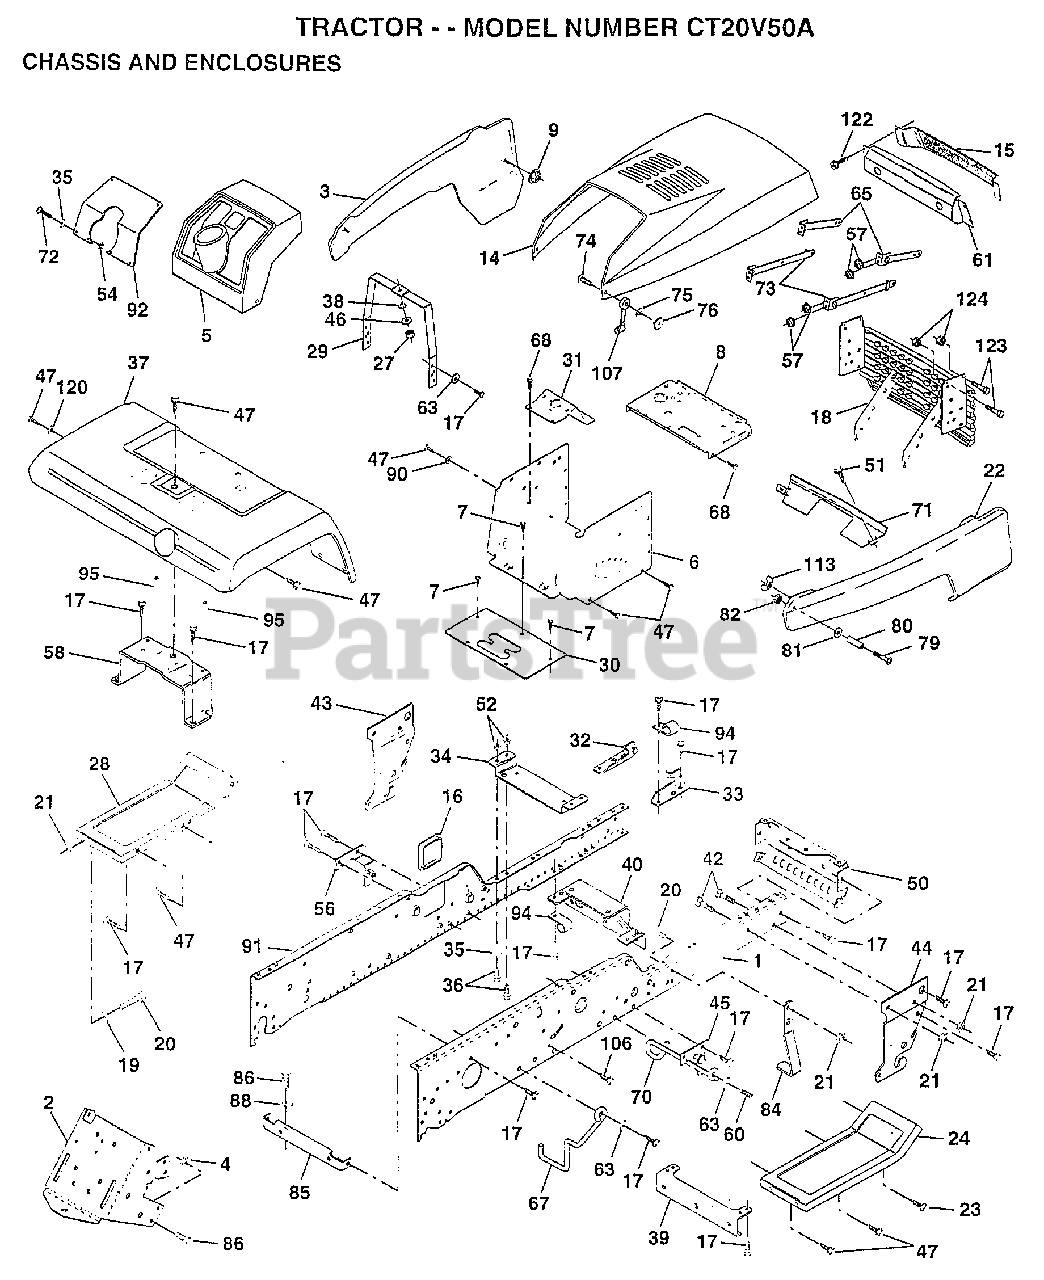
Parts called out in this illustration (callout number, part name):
2	DRAWBAR GT
3	PANEL.SD.LH.YT/GT
4	NUT GTV
5	DASHBOARD BLACK
6	DASH.1PC.LOWER
7	SCREW
8	SUPPORT.DASH.BTRY
9	PAL NUT LT
15	LENS.BAR.CLEAR
16	COVER ACCESS
17	SCREW
19	WASHER
20	BOLT
22	PANEL.SD.RH.YT/GT
24	FOOTREST.RH.LT/GT
28	FOOTREST.LH.LT/GT
29	DASH.SUPT.YP/HUSQ
30	SADDLE.SCR.6SP
31	BRAKET.SUPT.STEER
32	BRACKET ASM FRAME
33	BRACKET ASM FRAME
34	BRACKET.ENG.SUPT.
35	WASHER
36	BOLT
37	FENDER.PNT.MS-550
38	LOCKWASHER
39	BRACKET.AXLE.FRT.
43	BRACKET.SUS.FT.LH
44	BRACKET.SUS.FT.RH
46	WASHER PM
47	SCREW LT
50	BRACKET.CHASSIS.
51	SCREW CRT
57	NUT HXKEP 1/4X20
58	BRKT.ASM.FENDER
60	SCREW
63	WASHER
65	STRAP.ASM.HINGE.
67	GUIDE BELT TRANS
70	GUIDE.BELT.MID.SP
71	STRAP.PNT.GRILLE
72	SCREW
73	STRAP.ASM.HINGE.R
74	SCREW
75	LOCKWASHER
76	WELDNUT
79	SCREW
80	SPACER LT
81	WASHER
84	STOP.OVER.CENTER
85	BRACKET.SUPT.TRAN
86	BOLT
88	LOCKWASHER
90	LOCKWASHER
92	PLATE SLKSCR YP
94	CLIP GTV
95	NUT-PUSH YT
107	HOOD LATCH T
120	WASHER HYT
124	NUT
